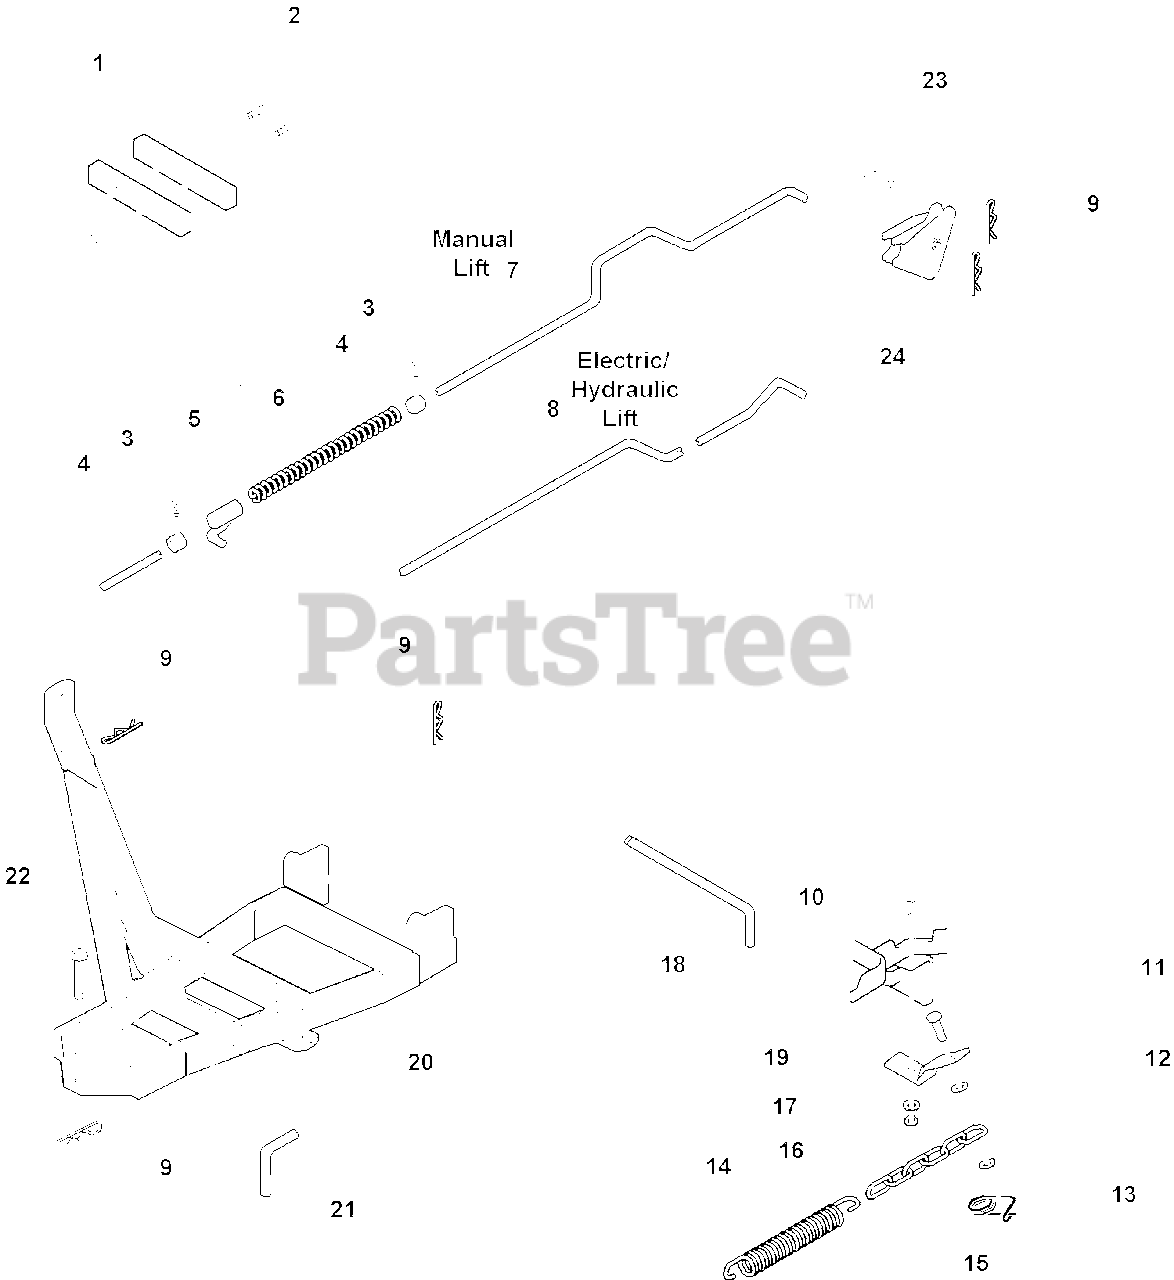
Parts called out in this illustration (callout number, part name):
1	BAR
2	CAPSCREW, Taptite, 5/16-18 x 1
3	SCREW, Set, 5/16-18 x 1/2
4	COLLAR
5	GUIDE ASSEMBLY
7	ROD Manual Lift
8	ROD, Elecrict / Hydraulic Lift
10	CAPSCREW, Hex Head 5/16-18 x 1
11	PIN
12	WASHER, 5/16
13	RETAINER, Pin
15	CHAIN, Link
16	NUT, Hex, 5/16-18
17	LOCKWASHER, 5/16
19	BRACKET
20	PUSH BAR ASSEMBLY
24	EXTENSION ASSEMBLY KIT
